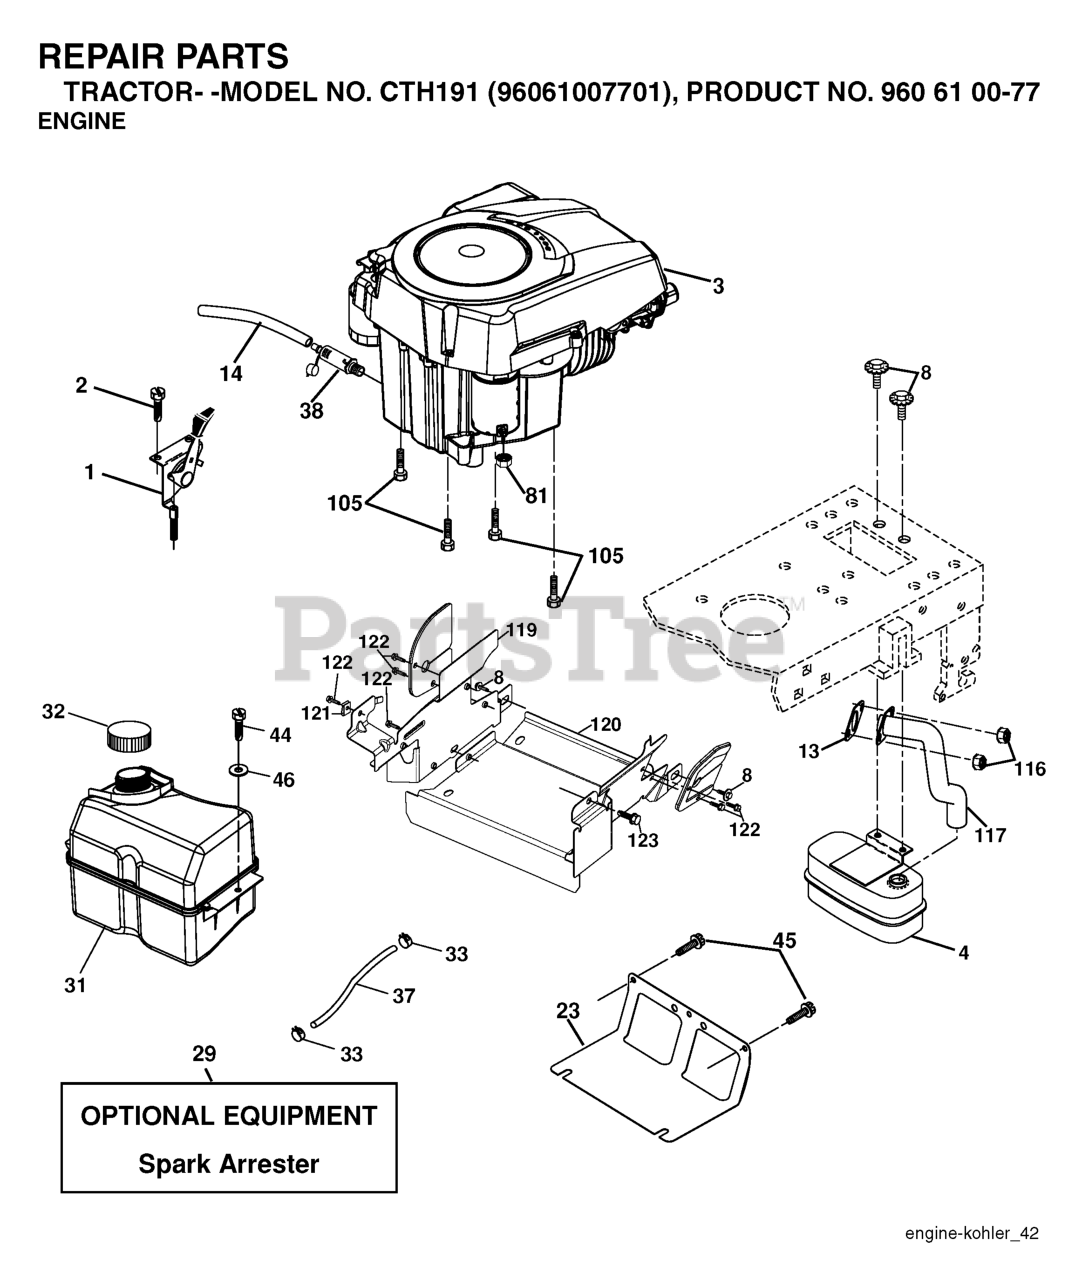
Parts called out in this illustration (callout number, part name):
1	CONTROL.THROTTLE.LT/YT
2	SCREW
4	MUFFLER.SINGLE.CYL.KOHL/B&S
8	BOLT.5/16-18UNCX3/4 W/SEMS.BLK
13	GASKET.EXHAUST.KOHLER
14	TUBE, DRAIN OIL ASM.
23	SHIELD.BROWNING.DBR.GUARD
29	KIT.SPARK ARRESTOR 794945 B&S
31	TANK FUEL
32	FUEL CAP
33	HOSE CLAMP
37	LINE.FUEL.20
38	PLUG DRAIN OIL EASY
44	SCREW HEXWSHR 1/4-20X3/4
45	SCREW, 3/8-16X3/4
81	NUT
105	SCREW 3/8-16X1
116	NUT.HEX.FLANGE.TOPLOCK
117	RP.TUBE.EXHAUST.KOHL.COURAGE
122	SCREW.1/4-20X5/8
123	SCREW, 5/16-18 X 1/2
